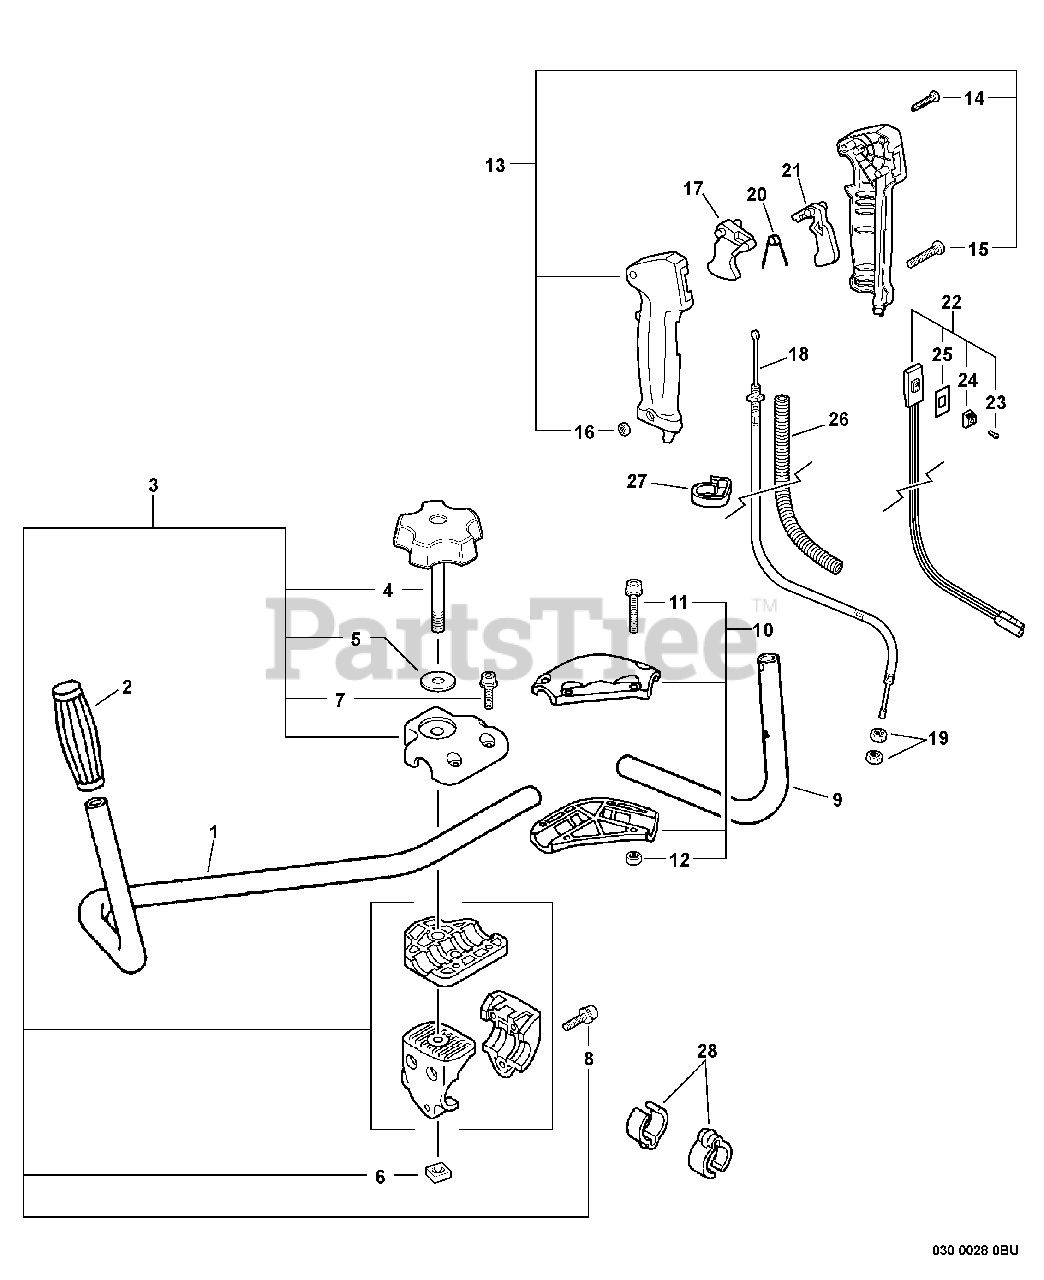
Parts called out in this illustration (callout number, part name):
1	HANDLE, FRONT - LEFT
2	GRIP, HANDLE
3	HANDLE BRACKET KIT
4	THUMBSCREW
5	WASHER - 8
7	SCREW - 5X20
8	SCREW - 5X30
9	HANDLE, FRONT - RIGHT
10	HANDLE BRACKET KIT
11	SCREW - 5X20
13	THROTTLE CONTROL ASSY
14	SCREW - 3X25
15	SCREW - 5X30
17	TRIGGER, THROTTLE
18	CABLE, THROTTLE
20	SPRING, LOCKOUT LEVER
21	LOCKOUT, THROTTLE
22	IGNITION SWITCH ASSY
23	SCREW - 3X10
24	KNOB, SWITCH - ORANGE
25	COVER, SWITCH - STOP
